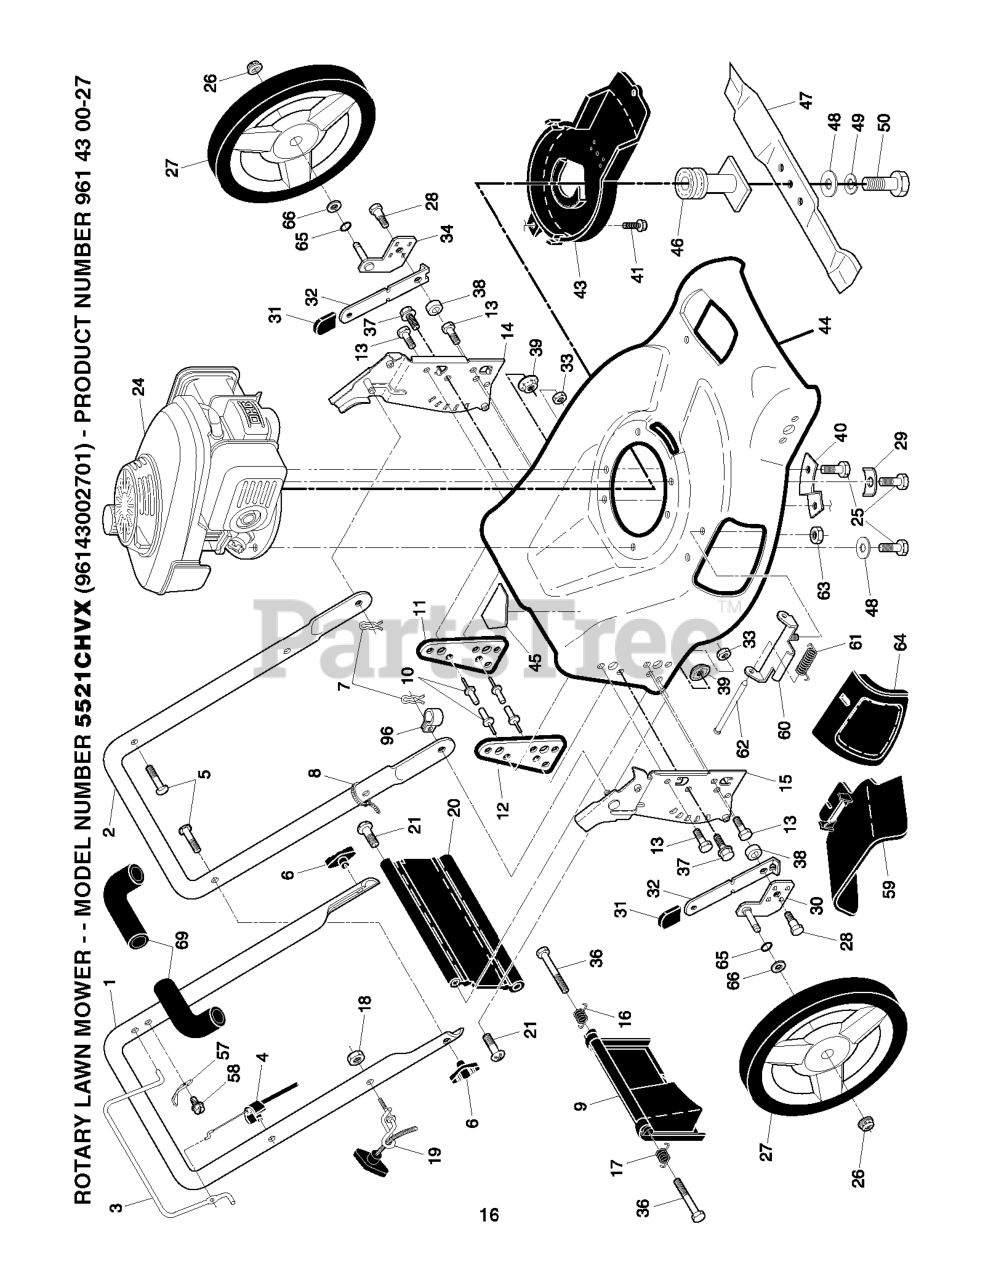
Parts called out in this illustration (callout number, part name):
1	RP HANDLE.ASM.UPPER.W/GRI
2	LOWER HANDLE
3	BAIL.DSTRT.FL.AW.CREAS.ORANGE
4	CABLE.ENGINE BRAKE.MZR
5	BOLT, HANDLE 5/16-18X1.75
6	HNDL.KNOB.GRAY
7	HAIRPIN COTTER
8	TIE GUIDE
9	REAR DOOR ASSEMBLY
10	RIVET BLIND
11	SUPPORT BRACKET LH
12	BRACKET.SUPRT.RH.21.FWGD
13	SCREW 14-20 X 5/8
14	BRKT.ASM.HNDL.21FGD.EZ
15	BRKT.ASM.HNDL.21FGD
16	SPRING.REAR.DOOR.EZ.21.LT
17	SPRING.REAR.DOOR.EZ.21.RT
18	NUT
19	RB GUIDE.ROPE.STD.BLK.ZIN WSL
20	REAR SKIRT
21	HINGE SCREW
25	BOLT 3/8-16X1-1/8
26	NUT.HEX.FLANGE.3/8-16.LOCKNUT
27	WHEEL ASSY
28	SHOULDER BOLT
29	WASHER.ENGINE.BZP
30	ARM.ASM.AXLE.H/W,RR.BZ
31	SELECTOR KNOB
32	SPRING.SELECTOR.21.FWG.ZINC
33	NUT.71038.31-18.HEX.NYLOCK
34	ARM.ASM.AXLE.H/W.LR.BZ
37	BOLT.FIN.HEX.5/16-18X3/4
38	WASHER.FLAT.34X1.38X22
39	NUT, HEX FLANGE 5/16-18
40	BRACKET
41	SCREW.HEX.WSH
43	DEBRIS SHIELD
44	HOUSING.21.FWD.ORANGE.WALK
45	DANGER DECAL
46	RP ADAP.BLDE/PULL
47	BLADE.21.PUSH/RWGD/FWGD
48	WASHER,HARDEN
49	LOCKWASHER
50	SCREW, HEX HD 3/8-24 X 1-3/8
57	BRACKET UPSTOP
59	DEFLECTOR.CLIPPIN.21.FGD
60	BRACKET.ASM.HINGE.21.FWGD.
61	SPRING.TORSION
62	ROD.HINGE.21
63	LOCKNUT.NYLOC.1/4-20
64	DOOR.MULCH.21.REAR.FWGD
65	O-RING..070X.487.NEOPRENE
66	WASHER.FLAT.1/2
69	GRIP.HANDLE.FOAM.WIDE.(1 SIDE)
96	CLIP.CABLE.BLK
